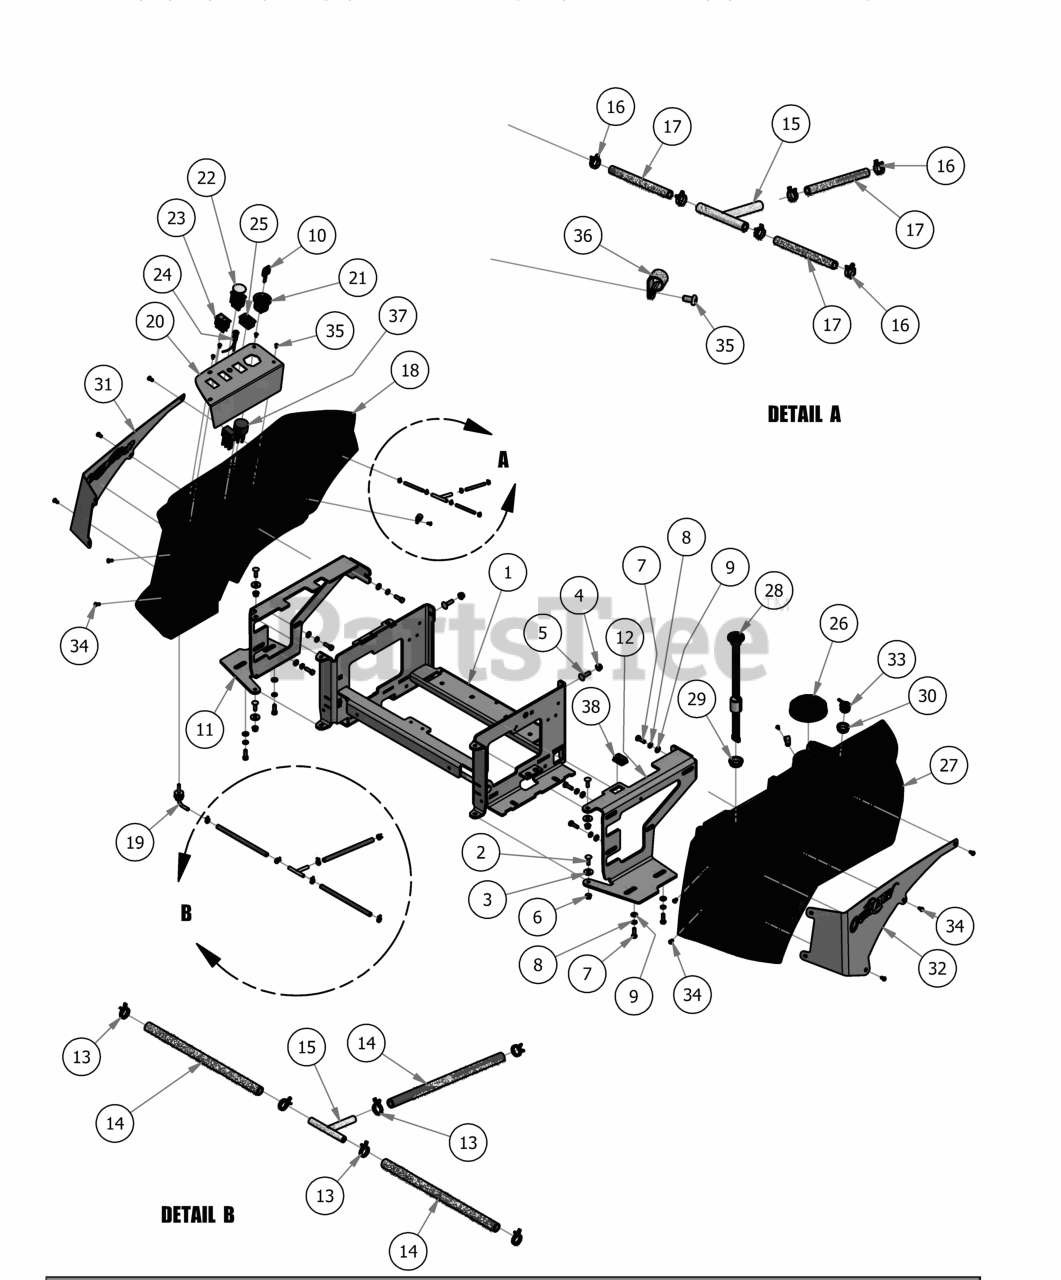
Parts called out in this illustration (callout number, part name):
1	2017 Outlaw Seat Bracket
2	5/16-18 x 1 Carriage Bolts Zinc
3	.360 ID Plastic Washer
4	3/8" Nylock Flange Nut
5	3/8" x 1 1/4" Carriage Bolt
6	5/16-18 Nylon Insert Flange Nut Zinc Orange Nylon
7	5/16" x 1" Bolt
8	5/16" Lock Washer
9	5/16" Flat Washer
10	Ignition Key
11	Outlaw 2015 Tank Support (Right)
12	Outlaw 2016 Tank Support (Left)
13	1/4 Fuel Hose Clamp
14	1/4" Fuel Line Hose
15	fuel line T
16	3/16 Vinyl Clamp
17	1/4" Vinyl Tubing
18	Outlaw 2015 Fuel Tank (Right)
19	Fuel Tank Hose Nipple w/Filter
20	Analog Control Panel Outlaw
21	Ignition Switch
22	PTO Switch
23	Rocker Deck Lift Switch
25	Tachometer
26	Fuel Cap (Kelch)
27	Outlaw 2015 Fuel Tank (Left)
28	Fuel Gauge w/Grommet
29	Grommet for Fuel Gauge
30	ROV Grommet
31	Outlaw Tank Panel (Right)
32	Outlaw Tank Panel (Left)
33	Rollover Valve - Black
34	1/4" x 1/2" BS C/S 18-8 SS
35	10-32 x 3/8" Button Socket Head Bolt
36	3/8 Cable Clamp-Black Nylon
37	Wiring Harness
38	Light Plug
